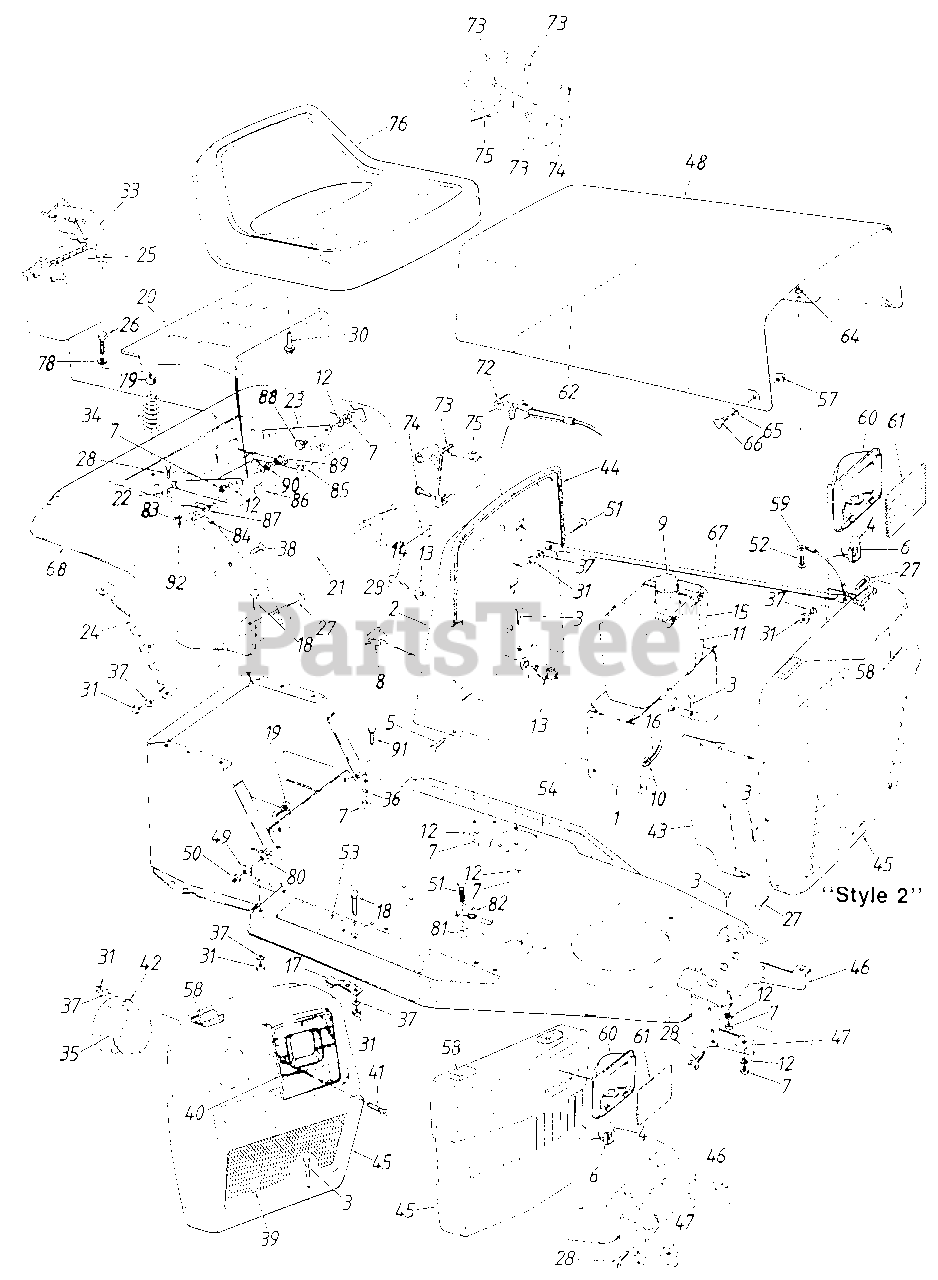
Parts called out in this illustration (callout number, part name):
1	Dash Panel Support Brkt.
4	Bulb
5	Hex AB-Tap Scr. 1/4 x .62"
6	Socket
7	Hex Nut 5/16-18 Thd.
8	Light Switch
9	Gas Gauge
10	Hose Clamp
11	Cable Tie
12	L-Wash. 5/16" I.D.
13	Ignition Switch
14	Ignition Key
15	Fuel Tank
16	Gas Line 24" Long
17	Blade Brake Ass'y.
18	Carriage Bolt 1/4-20 x .62"
19	Ribbed Neck Bolt 3/8-24 x .8"
20	Seat Pivot Brkt.
21	Rear Fender
22	Seat Hinge Support Brkt.-R . H .
23	Seat Hinge Support Brkt.-L. H .
24	Deck Lift Index Brkt.
25	Battery
26	Hex Self-Tap Screw 5/6-18 x 1" Lg.
27	Truss Mach. Scr. 1/4-20 x . 75 " Lg .
28	Hex AB-Tap Scr. 5/16 x .75" Lg.
30	Hex Self-Tap Scr. 3/8-16 x . 75 " Lg .
31	Hex Nut 1/4-20 Thd.
33	Battery Box w/Cover
34	Compression Spring
35	Headlight
36	Bell-Wash. 5/16" I.D.
37	L-Wash. 1/4" I.D.
38	Truss Wash. Hd. Tap Scr. #10 x .5" Lg.
39	Grille Insert
40	Bezel
41	C-Sunk Mach. Scr. 1/4-20 x 1.5"
42	Headlight Retainer
43	Side Panel-R.H.
44	Trim Strip 31" Lg.
46	Grille Mtg. Brkt.-L.H.
47	Grille Mtg. Brkt.-R.H.
50	Hex L-Nut 3/8-24 Thd.
51	Hex Bolt 1/4-20 x .62" Lg.*
52	Truss Mach. Scr. #10-24 x .5" Lg.
53	Foot Pad-R.H.
54	Foot Pad-L.H.
57	Lock Nut 1/4-28 Thd.
58	Foam Strip
59	Hood Stop
60	Headlight Housing
61	Lens
62	Hood Spring
64	Hex Sems Nut #10-24 Thd.
65	Spr. Wash. .39" I.D. x .62" O.D.
66	Shld. Bolt
67	Grille Support
68	Trim Strip 81" Lg.
72	Choke Control
73	Throttle Control Box
74	Truss AB-Tap Scr. #10 x .5"
75	Throttle Wire
76	Seat Assembly
78	Flat Wash. .344" I.D. x .88" O.D.
79	Bushing
80	Clamp
81	Hex L-Nut 1/4-20 Thd.
82	Clamp
83	Hex Tap Scr. #8 x .5" Lg.
84	Spring Switch
85	Ext. Spring 5.31" Lg.
86	Seat Lift Brkt.
87	Insulator Nut Plate
88	Shld. Bolt .437" Dia. x .162" Lg.
89	Shld. Bolt .437" Dia. x .268" Lg.
90	Spr. Wash. .445" I.D. x .751' 0. D.
91	Hex Bolt 5/16-18 x 518" Lg.*
92	Fiber Washer
